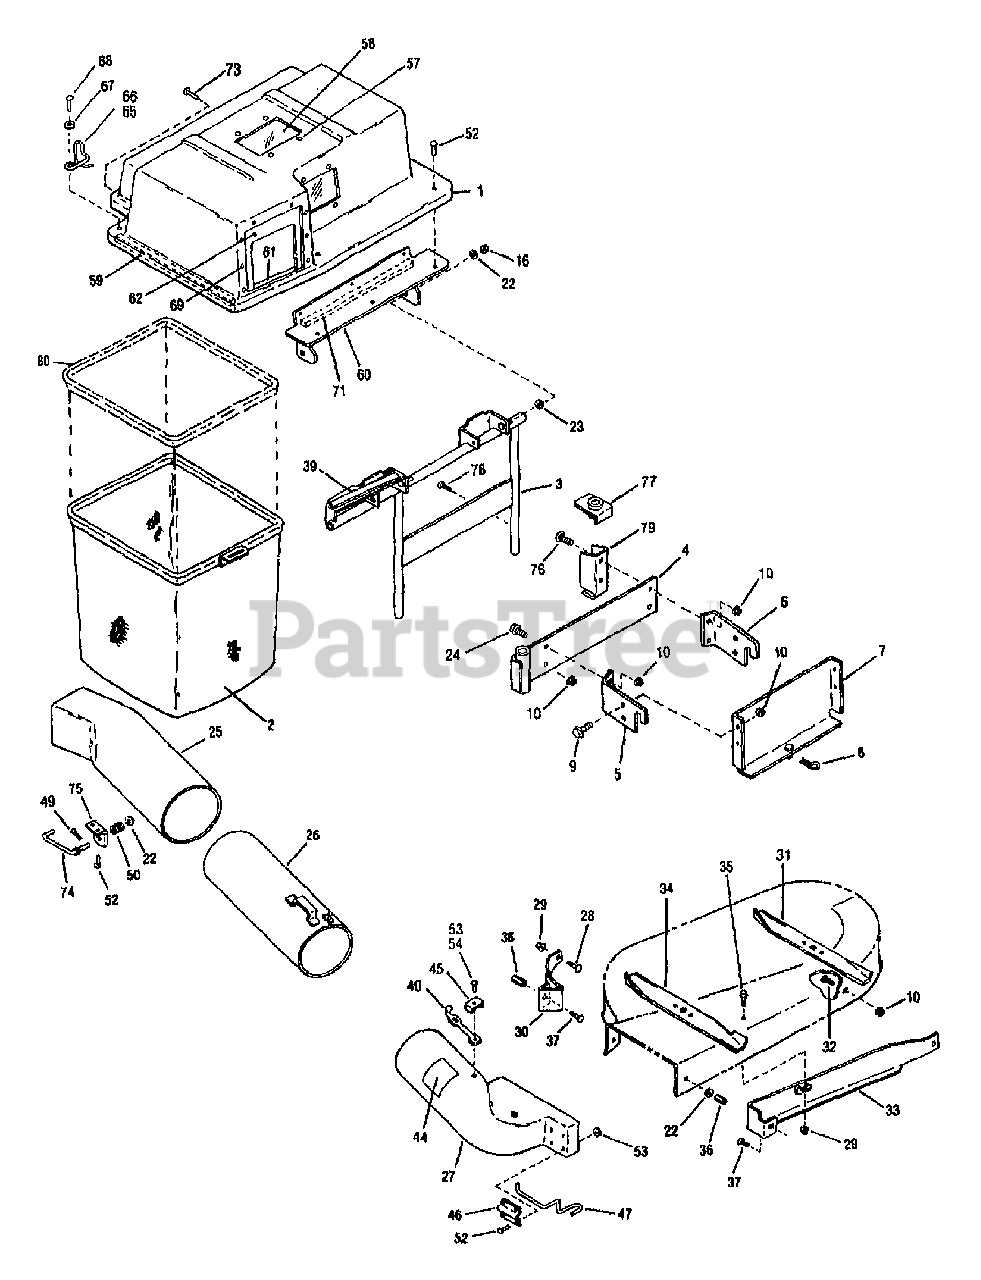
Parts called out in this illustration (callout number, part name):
1	ASSM-CVR GRASS BAG
2	ASSM-GRASS BAG
3	ASSM-BAG SUPPORT
4	ASSM-SUPPORT PLATE
5	PLATE-HITCH LH
6	PLATE-RIGHT HITCH
7	ASSM-SUPPORT HITCH
8	PIN-HITCH .125X2.56 ZP
9	SCR-HFLK 5/16-18X.75 ZP
10	NUT-HFLK 5/16-18 ZP
16	NUT-TOP/LK 5/16-18 ZP
22	WASHER-FLAT 5/16 SAE
23	WASHER-.87X.34X.06 NYLON
24	SCR-HFLK 5/16-18X1.00 ZP
25	ELBOW
26	ASSM-GRASS GUIDE
27	ASSM-DISCHARGE CHUTE
28	SCR-CARR 1/4-20X.75 G2 ZP
29	NUT-HF/LK 1/4-20 ZP
30	BAFFLE-REAR
31	BLADE-MWR LH HILIFT
32	SCR-CARR 5/16-18X.75 G2 ZP
33	BAFFLE-FRONT
34	BLADE-MWR RH HILIFT
35	SCR-HH 1/4-20X.625
36	NUT GUIDE 5/16-18 ZP
37	SCR-CARR 5/16-18X.62 G2 ZP
39	SEAL-COVER 9.5"
40	LATCH-RUBBER
44	DECAL-WARNING
46	LEVER-CLAMP
47	LEVER-LOCK
49	PIN-ROLL .093 DIAX.62
50	SPRING
52	RIVET-POP 3/16"DIA
53	WASHER-.505X.22X.05
54	POP-RIVET
57	RIVET-POP
58	WINDOW
60	ASSM-HINGE SUPPORT
61	CHUTE REINFORCEMENT
62	GASKET-CHUTE
65	COVER-LOCK RH
66	COVER-LOCK LH
67	WASHER-.88X.2X.059
68	RIVET-POP 3/16X1/2
69	RIVET-POP .125
71	SEAL-COVER
73	RIVET-POP
75	BRACKET-CHUTE
76	SCR-CARR 5/16-18X1.0 G2 ZP
77	ASSM-COLLAR STOP
78	SCR
79	SUPPORT-TUBE
80	ASSM-FRAME GRASSBAG
